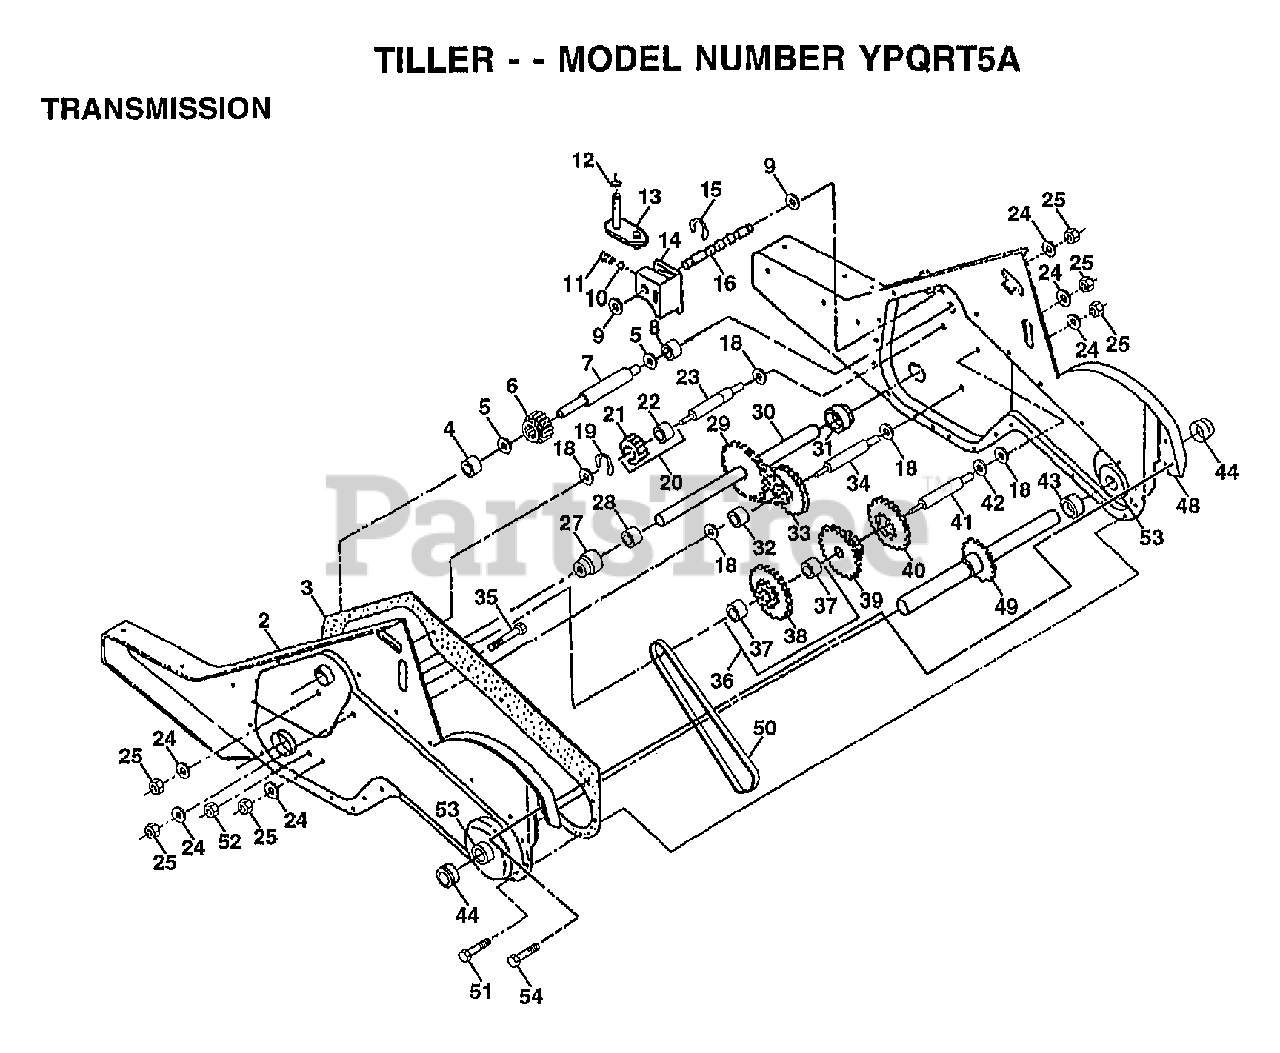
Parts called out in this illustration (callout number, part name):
2	GEARCASE LH W/BEARING
3	GASKET.GEARCASE
4	NEEDLE BRNG LT
5	"T, BEARING"
6	GEAR PINION INPUT
7	"SHAFT.INPUT.""D"""
8	"TI, BEARING"
9	WASHER SEAL
11	SPRING-SHIFT CRT
12	O-RING TI
13	BRACKET ASM SHIFT
14	SHIFT FORK TI
15	KLIP RING
16	SHAFT.SHIFTER
18	WASHER
19	KLIP RING
20	GEAR ASSY CRT
21	GEAR-REV IDLR CRT
22	NEEDLE BEARING TI
23	SHAFT CRT
24	LOCKWASHER
25	NUT.ASF.HEX.7/16
27	BEARING.SHAFT.LH.
28	BUSHING TI
29	CHAIN CRT
30	GROUND SHAFT ASSY
31	BEARING.SHAFT.RH.
32	SPACER TI
33	SPRCKT 8 GEAR CRT
34	SHFT 2ND RED. CRT
35	SCRW WHIZ LOK CRT
36	SPROCKET.ASM.W/BR
37	BEARING
39	GEAR TI
40	GEAR TI
41	REDUCTION SHFT TI
42	BRNG RACE
43	SPACER TI
44	SEAL ASM-OIL
48	GEARCASE RH W/BEARING
49	TINE SHAFT
50	CHAIN.50 LINK TI
51	SCREW
52	NUT.HEX.5/16-18
53	KIT.BEARING
54	SCREW 1/4-20X3/4
